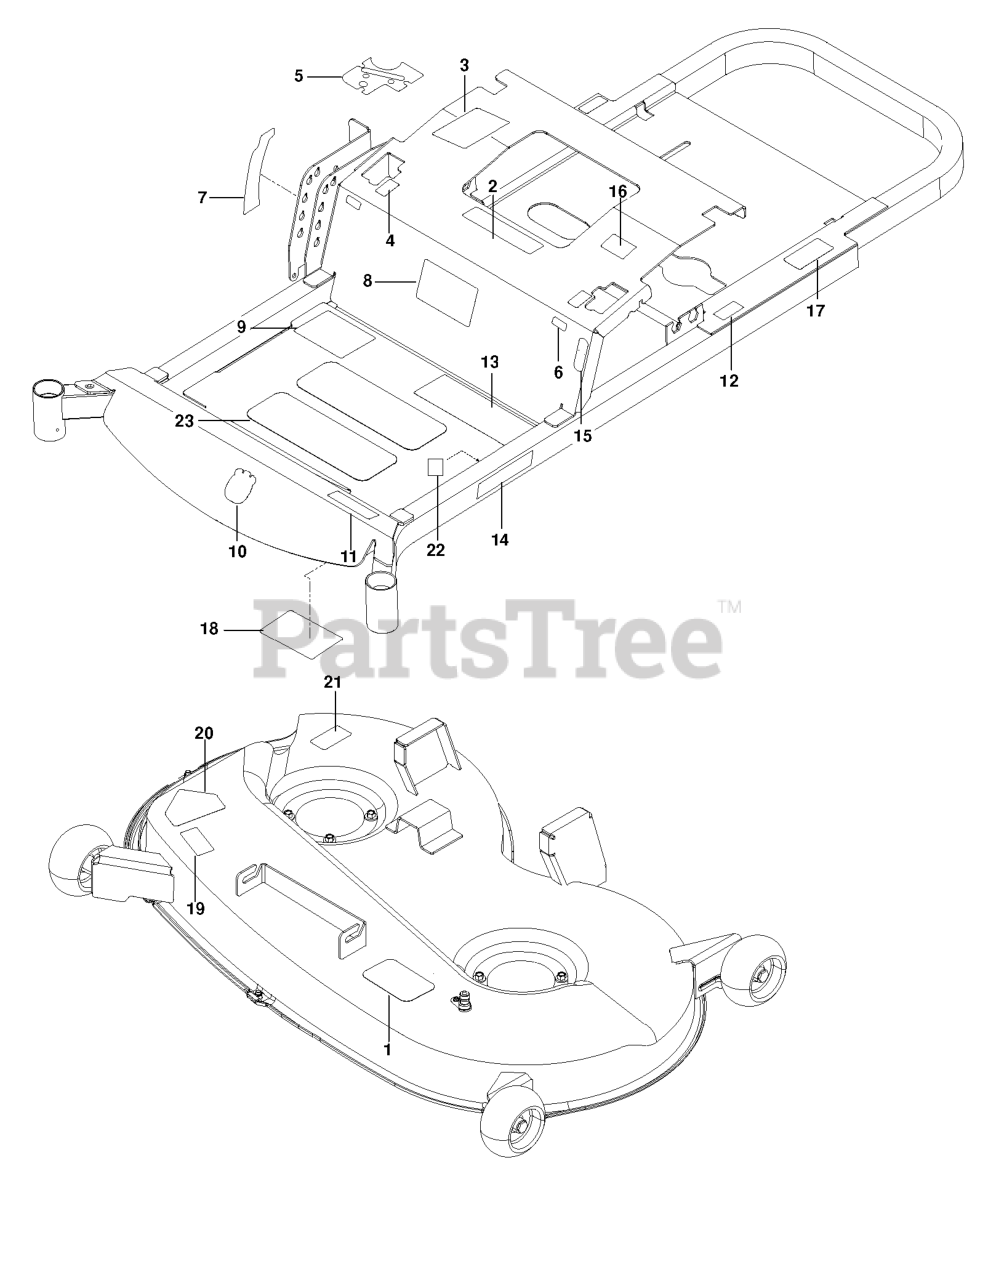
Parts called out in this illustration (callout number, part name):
1	DECAL, BELT ROUTING
2	EURO DECAL-BATTERY WARNIN6
3	DECAL, CUSTOMER RESPNSIBILITY
4	DECAL, MOTION CONTROL
5	DECAL, CTRL PANEL, HUSQ
6	DECAL, F.S.T.
7	DECAL, DECK HEIGHT, HUSQ
8	DECAL, START
9	DECAL, WARNING
10	DECAL.AUGER.HUSQ.CROWN.SNOW
11	DECAL RZ4622T
12	DECAL, ECM, AUSTRALIA
13	DECAL, SAFETY WARNING
14	RP.DECAL.BADGE.170MM.TEXTLOGO
15	DECAL, PARK BRAKE
16	DECAL, EXITING MOWER
17	DECAL, DO NOT TOW
18	DECAL, SERVICE
19	DECAL, EURO SEVERING
20	DECAL, CPSC
21	DECAL, CAUTION
22	DECAL 80 DBA
23	ANTI-SKID PAD
